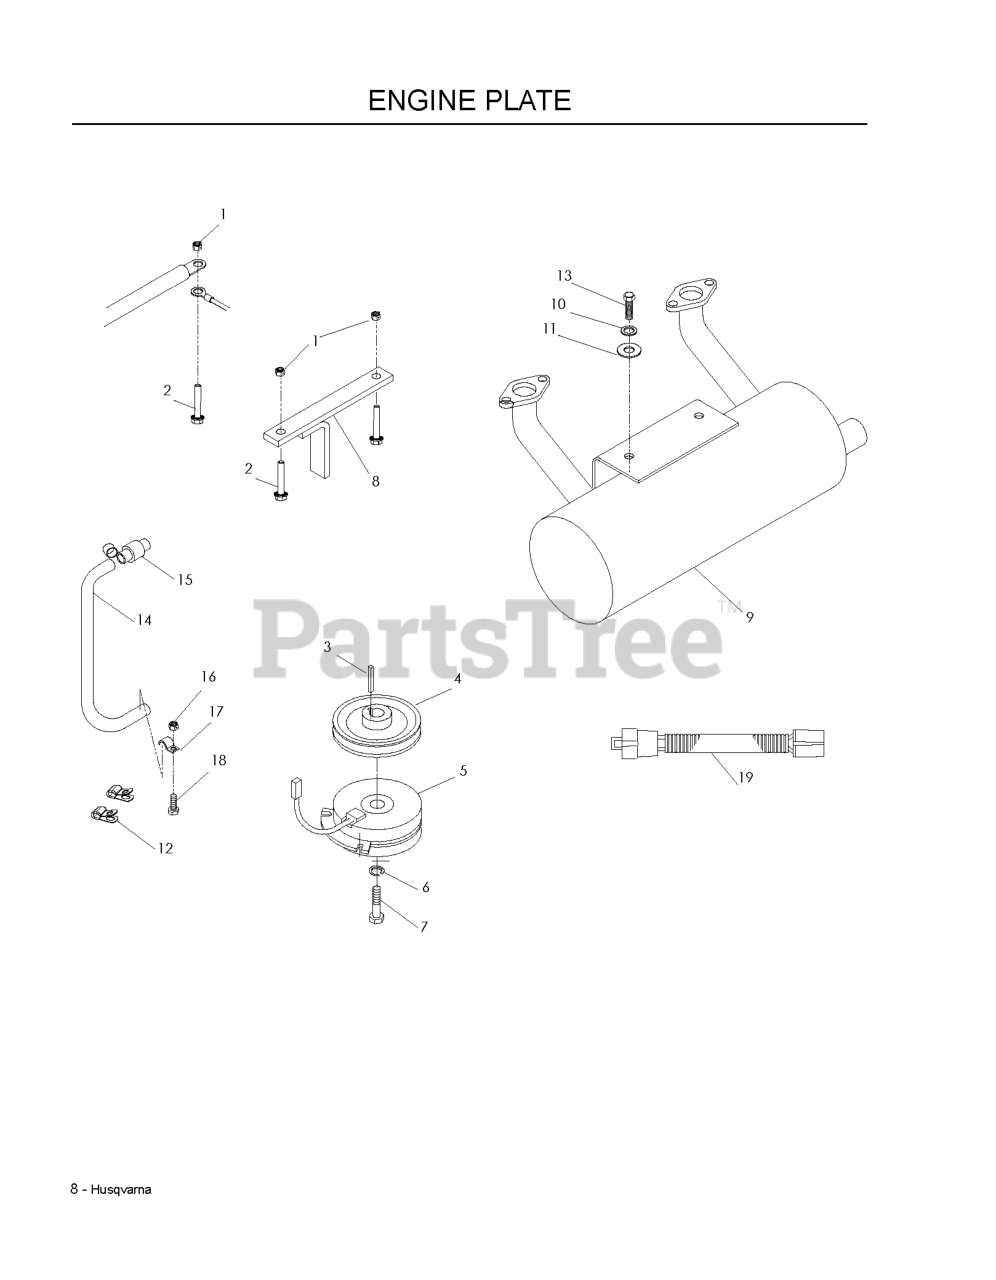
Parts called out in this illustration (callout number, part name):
1	NUT 5/16C CENTERLOCK
2	HCS 5/16-18 X 1-3/4 SERATED
3	KEY 1/4" SQ X 1 7/8"
5	ELECTRIC CLUTCH W/CABLE
6	WASHER 7/16 LOCK
7	BOLT 7/16F X 2 1/2
8	CLUTCH TIE DOWN
9	MUFFLER KOHLER GEN II
10	WASHER.LOCK.HVY.HLCL.SPR.5/16
11	WASHER 5/16 FLAT
12	DOUBLE TUBE CLAMP
13	HCS 5/16C X 3/4
14	OIL DRAIN HOSE
15	OIL DRAIN FITTING
16	NUT 1/4C CENTER LOCK
18	HCS 1/4C X 3/4 HCS
19	KOH PIGTAIL
